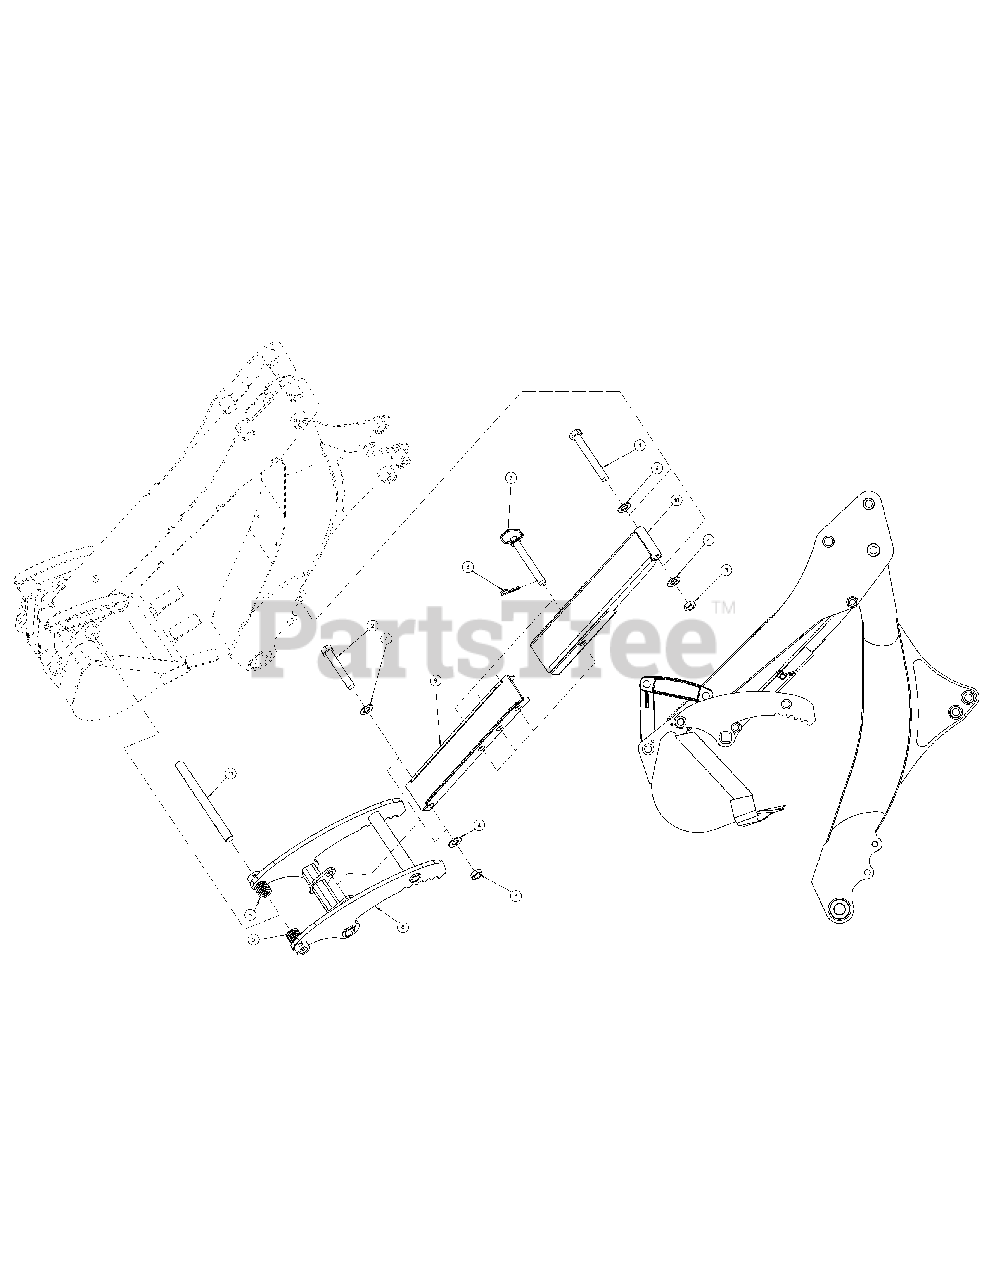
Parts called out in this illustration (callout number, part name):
1	Bolt, 1" NF x 8" Gr.8
2	Bolt, 1" NF x 6-1/2" Gr.8
3	Nut, 1" NF
4	Flat Washer, 1" SAE
5	Machine Bushing, 1-7/8"OD x 1-1/4"ID x 18Ga
6	Hair Pin Clip #6
8	Mechanical Thumb Weldment
9	Lower Column Weldment
10	Upper Column Weldment
11	Bucket/Thumb Link Pin
